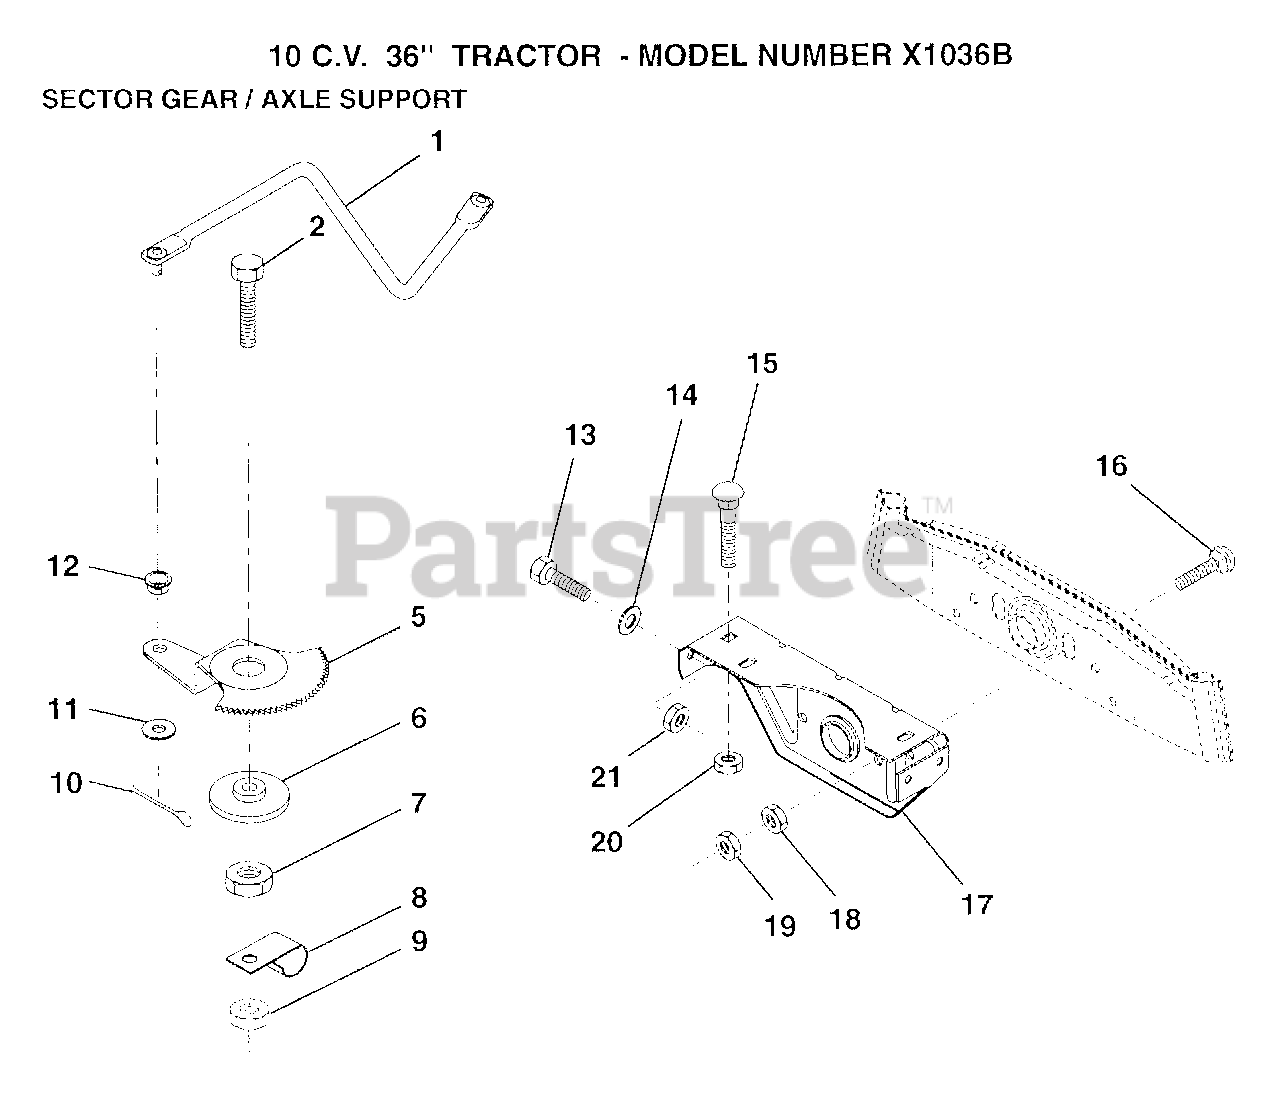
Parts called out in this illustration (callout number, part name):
2	"BOLT,HEX"
5	GEAR SECTOR
6	BUSHING
7	NUT
8	CLIP INSULATOR
9	NUT LTV
10	COTTER PIN
11	WASHER
12	BUSHING.DRAGLINK
13	BOLT
14	WASHER
15	BOLT
16	BOLT
17	"SUPT,FRT AXLE"
18	NUT.HEX.3/8-16UNC
19	LOCKNUT
